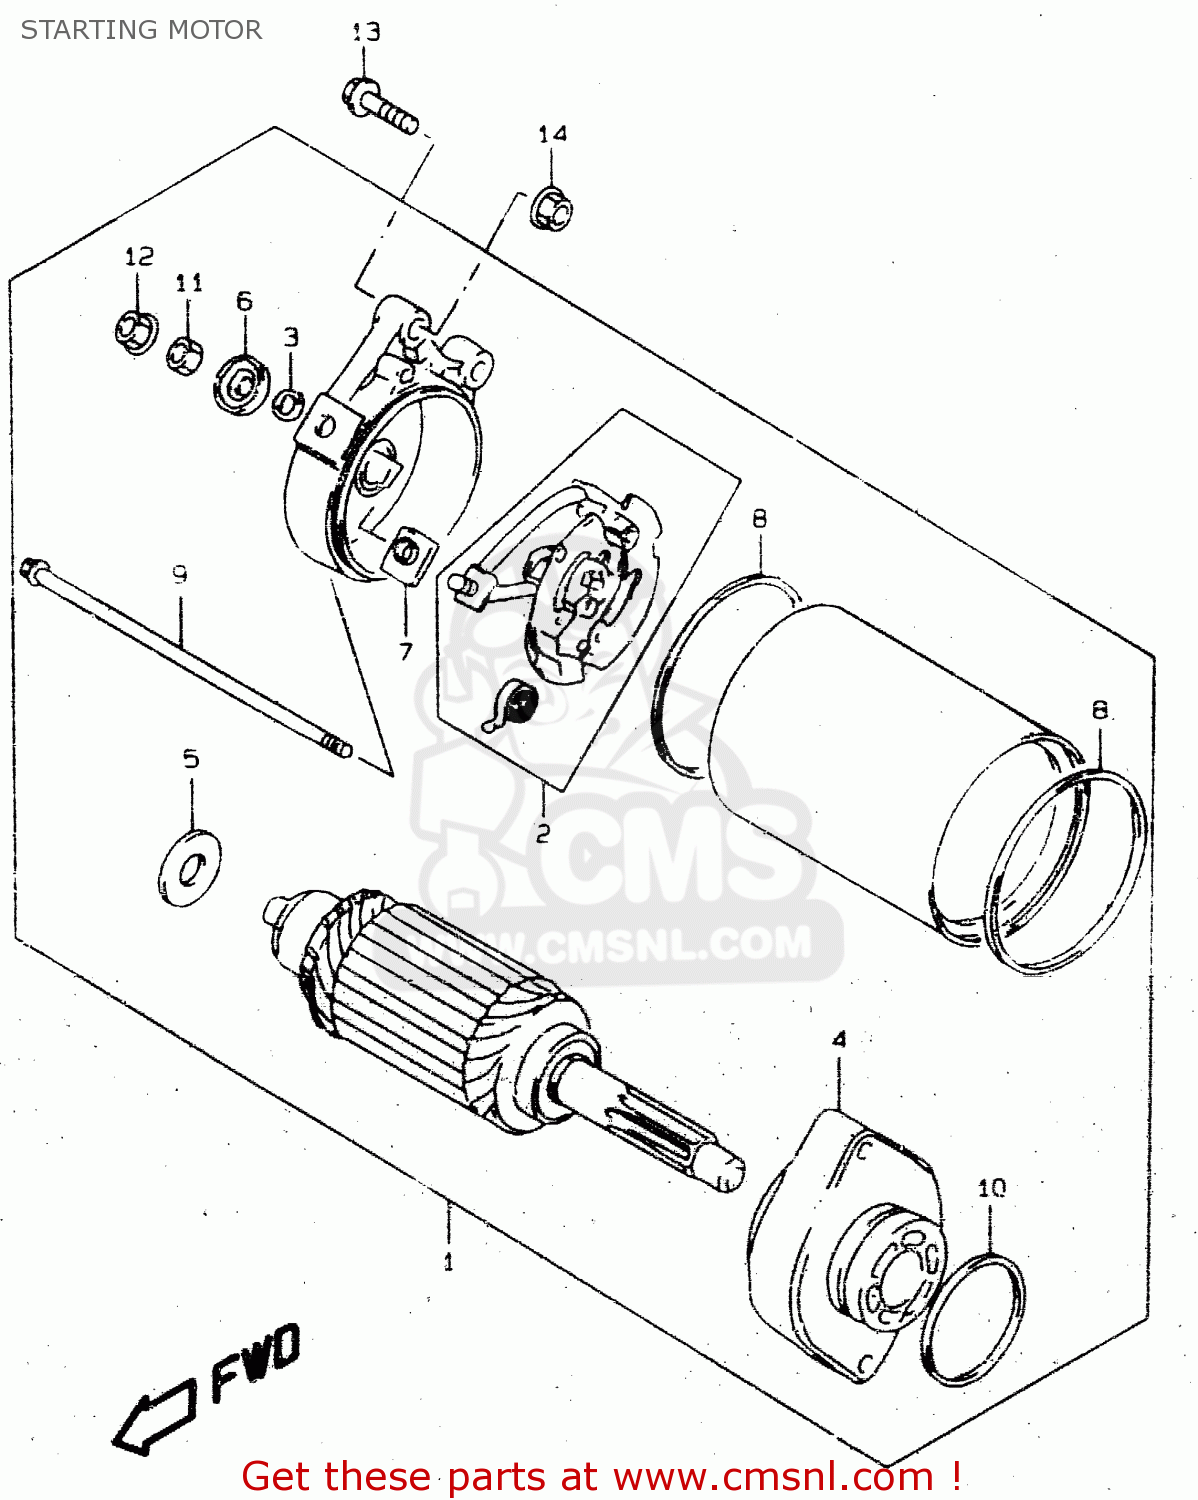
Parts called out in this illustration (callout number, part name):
1	MOTOR ASSY,STARTING
2	HOLDER SET,BRUSH
3	O RING
4	BRACKET SET
5	SHIM SET,STARTING MOTOR
6	BUSHING
7	BUSHING
8	O RING
9	BOLT
10	O-RING (D:2.1 ID:34.7)
11	NUT
12	NUT
13	BOLT
14	NUT
